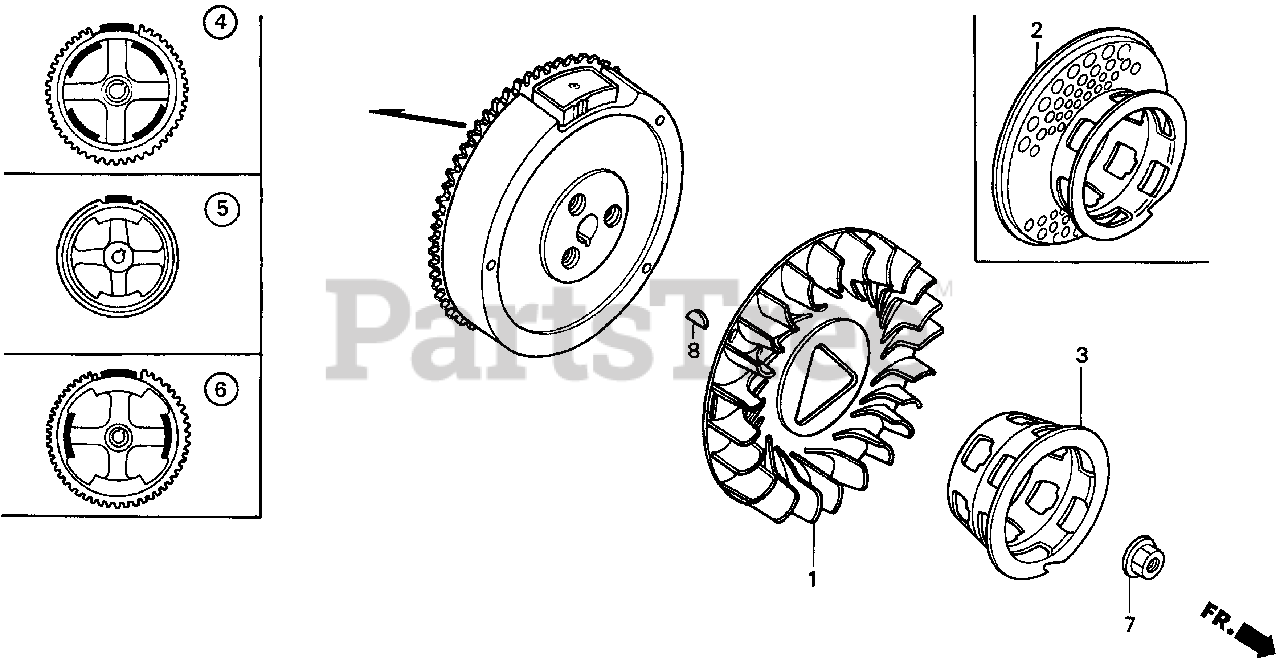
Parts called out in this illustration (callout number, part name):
1	FAN, COOLING
3	PULLEY, STARTER
6	FLYWHEEL (SEL-LAMP)
7	NUT, SPECIAL (16MM) (1)
7	NUT, SPECIAL (16MM)
8	KEY, SPECIAL WOODRUFF (25X18)
